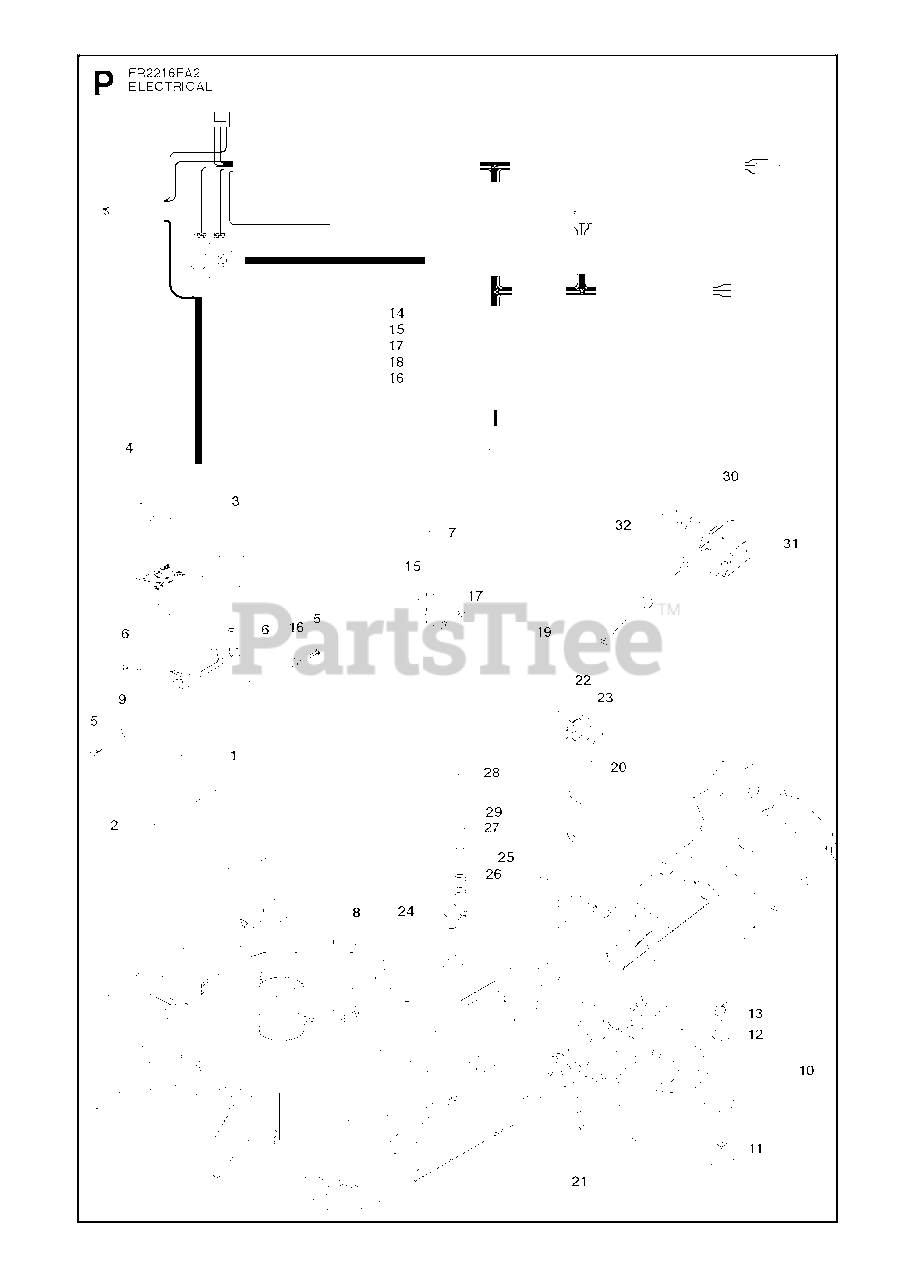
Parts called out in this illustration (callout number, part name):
5	SCREW EHHM
10	IGNITION SWITCH
11	IGNITION SWITCH
12	NUT
13	IGNITION KEY
19	WIRING
27	SPACER TUBE
28	SCREW
29	WASHER BRB 8.4X17
30	MICRO SWITCH
